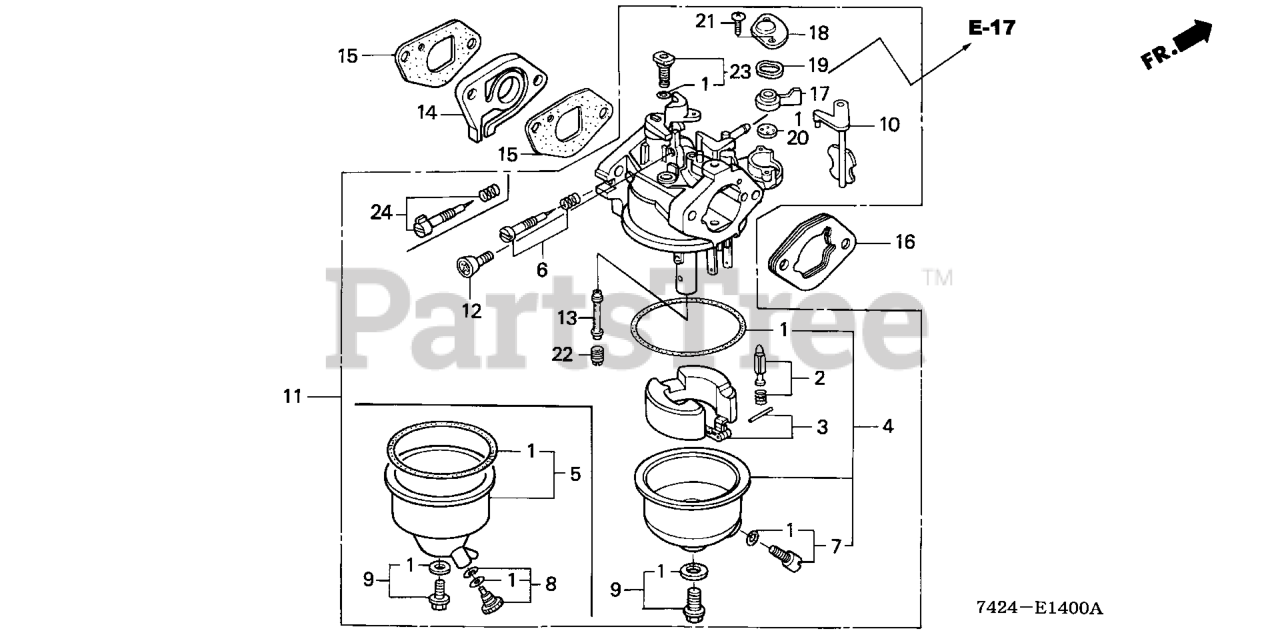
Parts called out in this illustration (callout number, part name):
1	GASKET SET (CARBURETOR NO.)
2	VALVE SET, FLOAT (CARBURETOR NO.) (SEAT NOT INCLUDED)
3	FLOAT SET
5	CHAMBER SET, FLOAT (CARBURETOR NO.)
8	SCREW SET, DRAIN (CARBURETOR NO.)
9	SCREW SET B
9	SCREW SET
10	CHOKE SET
11	CARBURETOR ASSY. (BE03C B)
11	CARBURETOR ASSY. (BE03C C)
12	SCREW, THROTTLE STOP
13	NOZZLE, MAIN
14	INSULATOR, CARBURETOR
15	GASKET, INSULATOR
16	SPACER, CARBURETOR
17	LEVER, PETCOCK (CARBURETOR NO.)
18	PLATE, LEVER SETTING (CARBURETOR NO.)
19	SPRING, PETCOCK LEVER (CARBURETOR NO.)
20	GASKET, VALVE
21	SCREW, PAN (3X6)
22	JET, MAIN (#58) Use from Engine SN BE30B E.
22	JET, MAIN (#52)
22	JET, MAIN (#55) (CARBURETOR NO.) Use up to Engine SN BE03A J.
23	JET SET, PILOT (#38)
24	SCREW SET (Honda Code 4219879). (CARBURETOR NO.)
